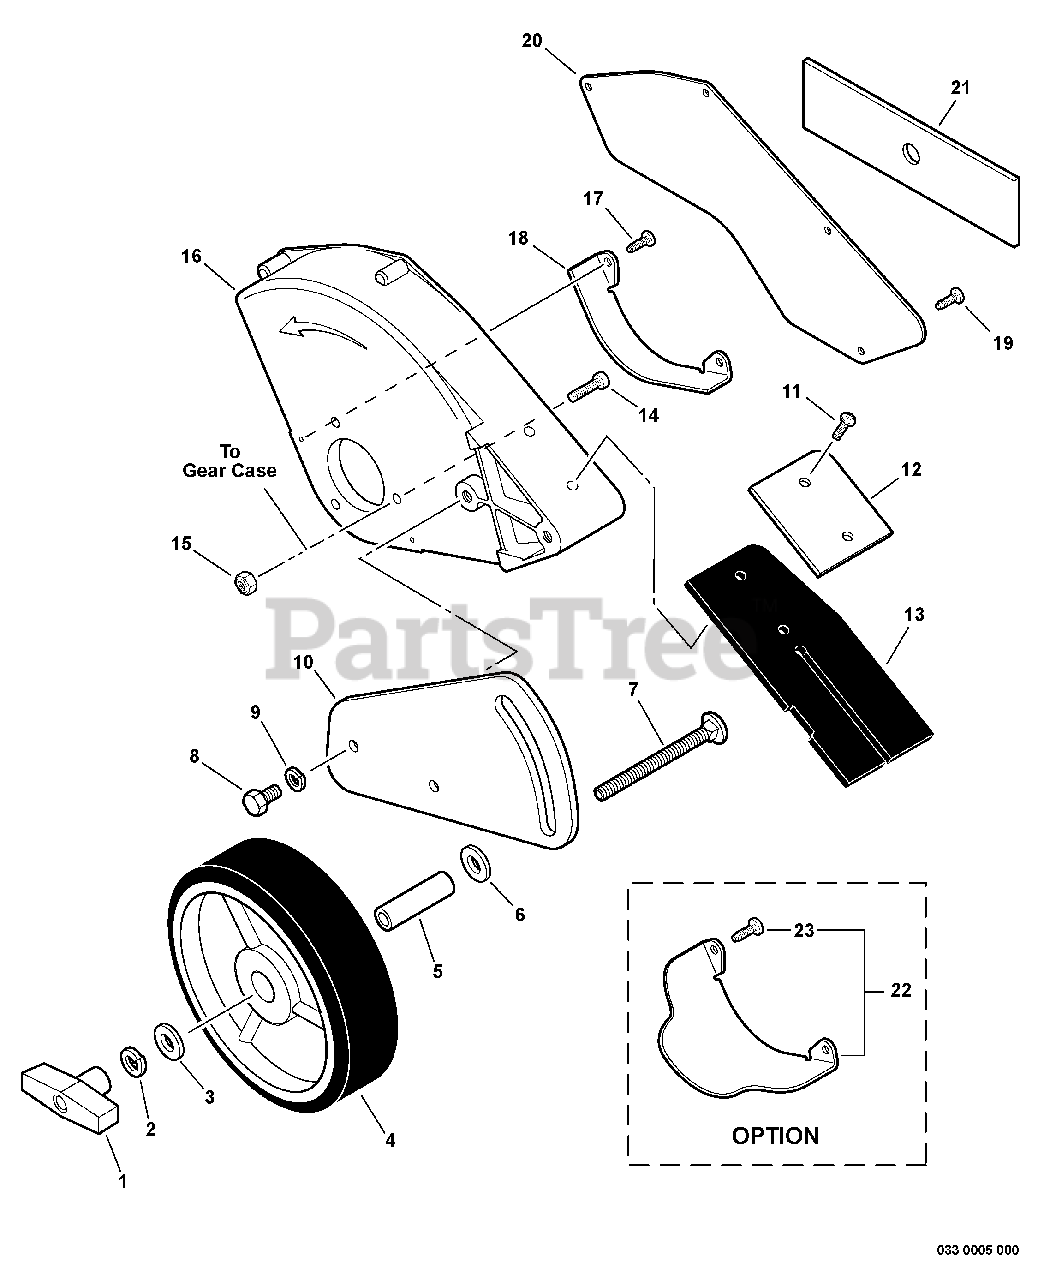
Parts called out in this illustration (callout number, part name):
1	KNOB, FASTENER
2	WASHER, SPRING 8
4	WHEEL
5	COLLAR 12
6	WASHER, SPRING 10
7	BOLT 5/16"-18×2-1/2"
8	BOLT 8×14
9	WASHER, SPRING 8
10	BRACKET, WHEEL
11	BOLT 4×14
12	PLATE, FLAP
13	FLAP, DEBRIS
14	BOLT 5×22
15	NUT, LOCK M5
16	NEW BLADE SHIELD
17	BOLT 4×12
18	GUARD, SHIELD
19	BOLT 4×12
20	SHIELD, DEBRIS
21	BLADE, EDGER
22	GUARD KIT, SHIELD
23	SCREW 4×12
